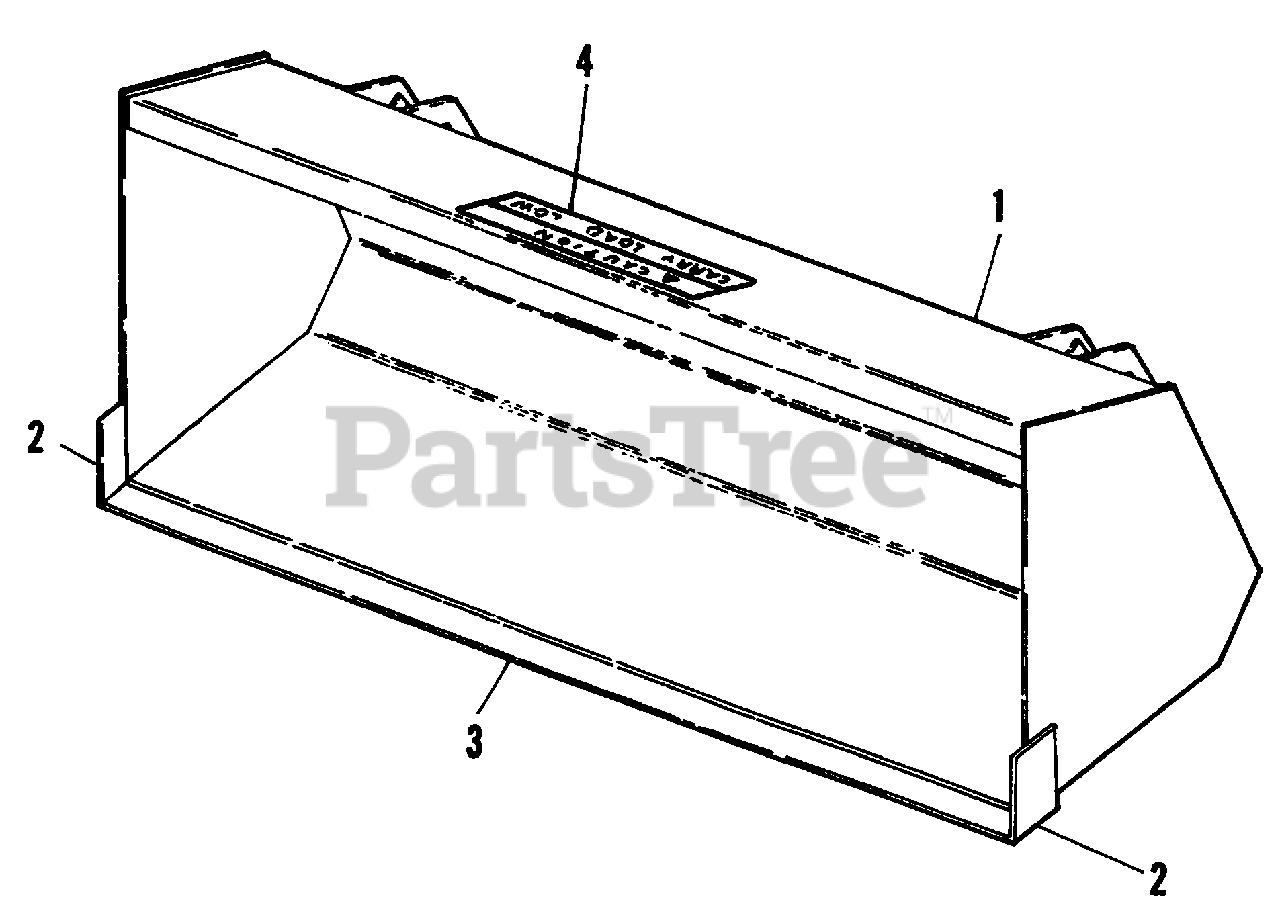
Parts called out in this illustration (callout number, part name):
1	38" BUCKET
1	48" BUCKET
2	EDGE, Side Cutting
3	EDGE, 38", Bottom Cutting
3	EDGE, 48", Bottom Cutting
4	DECAL, Caution
